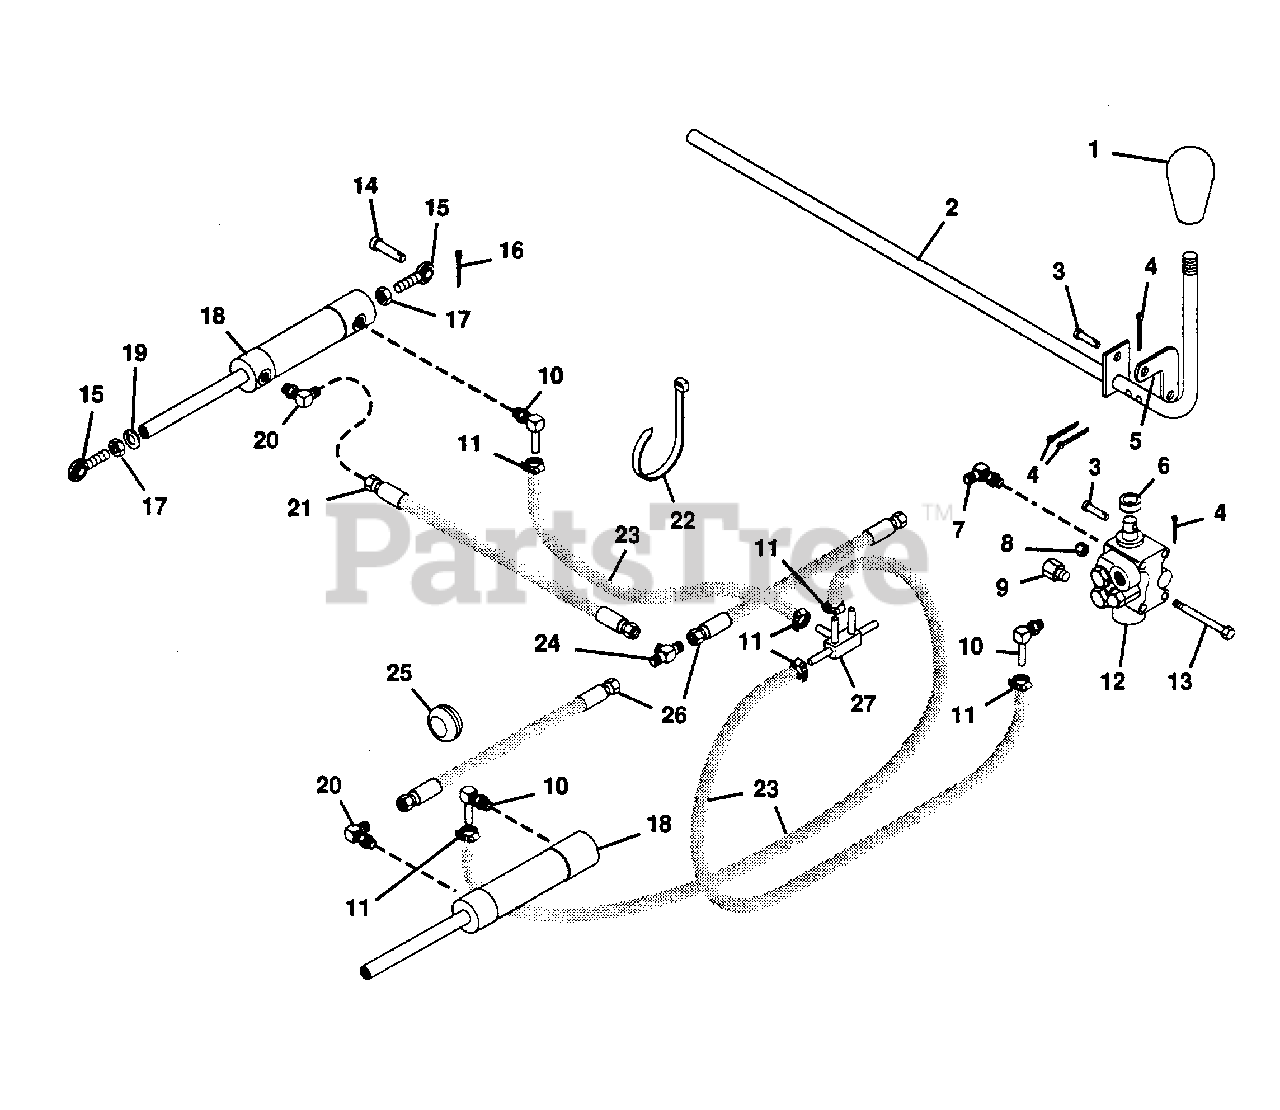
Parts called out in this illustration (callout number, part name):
1	Knob, PTO
2	Weldment, Lift Lever
3	Pin, Clevis
4	Pin, Cotter .094x.75
5	Rod, Hydraulic Control
6	Bush., St. .700x1.00x.300 Stl.
7	Adapter
8	Nut, Lock 1/4-20
9	Plug, PH 05PO-4
10	Adapter, 4601-6-6
11	Clamp, Hose
12	Valve, Hydraulic
13	Bolt, Hex 1/4-20x2.75
14	Pin, Clevis .50x1.330
15	Assembly, Rod End R.H.
16	Pin, Cotter .125x1.25
17	Nut, Jam 1/2-20
18	Cylinder, Lift
19	Washer, Lock 1/2 Reg.
20	Adapter, PH 2503-6-6
21	Assembly, Hydraulic Hose
22	Tie Wrap, Black
23	Hydraulic Hose,
24	Adapter Tee
25	Grommet, 1.25
26	Assembly, Hydraulic Hose
27	Manifold
